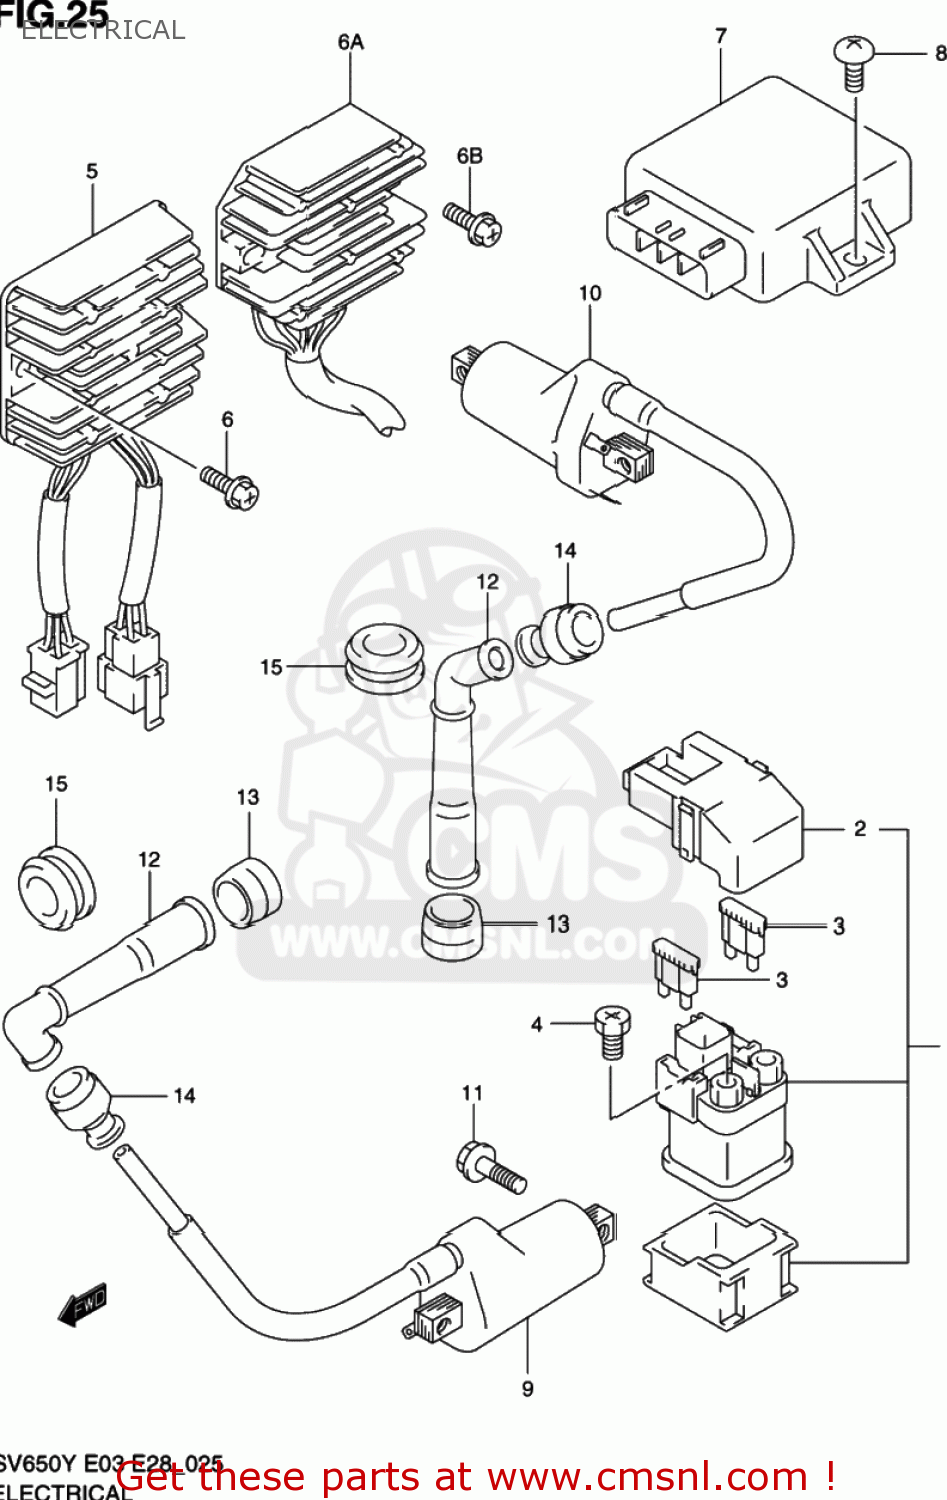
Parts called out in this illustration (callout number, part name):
1	RELAY ASSY,STARTING MOTOR
2	COVER,RELAY ASSEMBLY
3	FUSE(30A)
4	SCREW(6X8)
5	RECTIFIER ASSEMBLY
6	SCREW
6A	RECTIFIER ASSY
6B	BOLT
7	IGNITOR ASSY
8	SCREW
9	COIL ASSY,IGNITION(L:240)
10	COIL ASSY,IGNITION(L:420)
11	BOLT
12	CAP,SPARK PLUG
13	SEAL,SPARK PLUG CAP
14	SEAL,HIGH TENSION CORD
15	COVER,SPARK PLUG CAP
